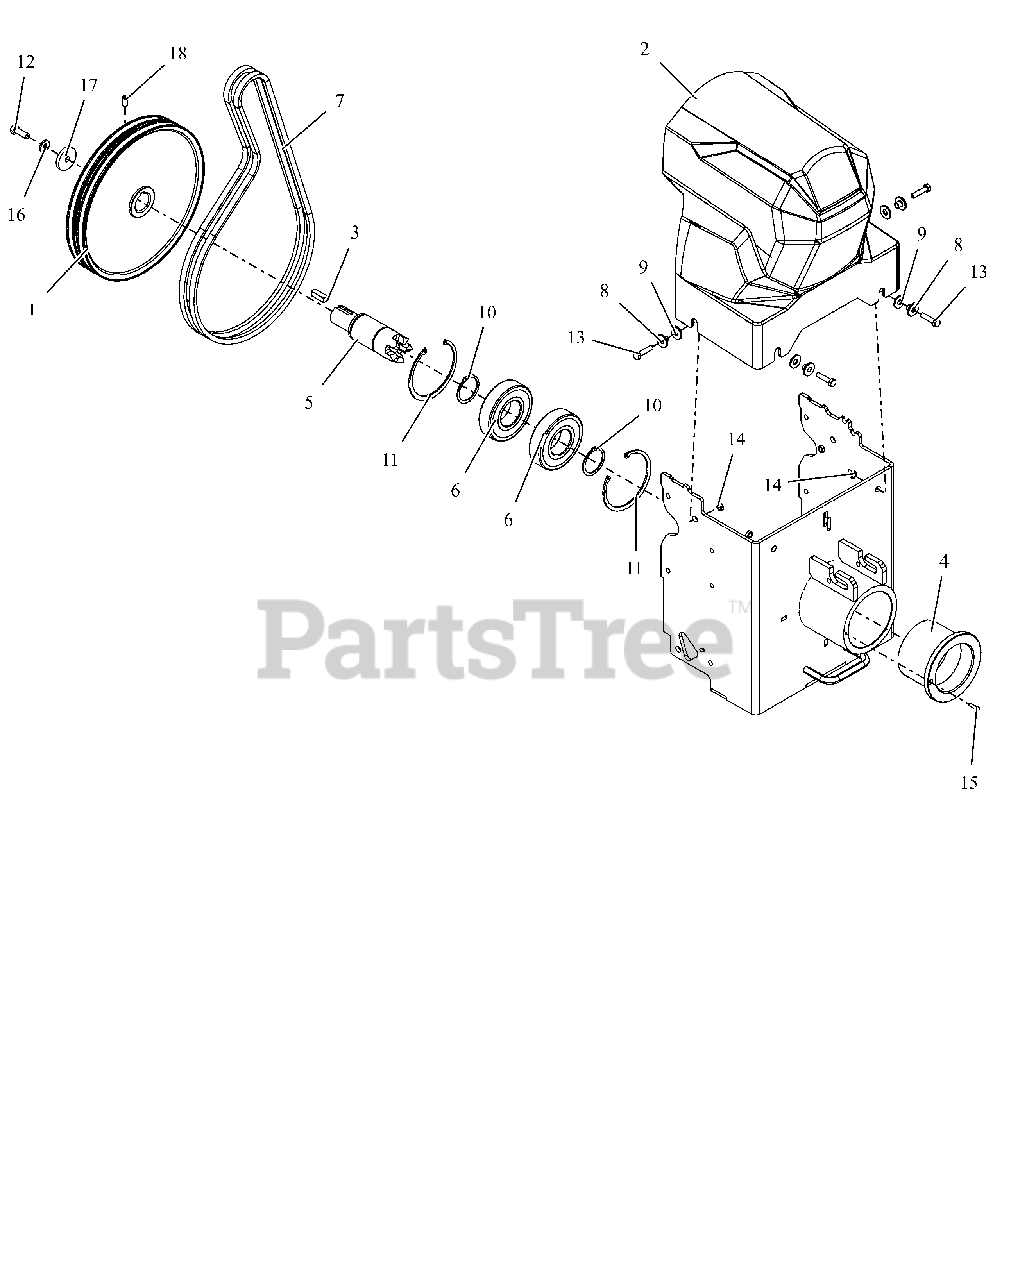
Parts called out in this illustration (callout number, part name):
1	PULLEY, DBL PTO INPUT
2	COVER, FRONT BELT
3	KEY-SQ .38X1.25X.375
4	BUSHING, OUTPUT
5	SHAFT, PTO
6	BRG, BALL 6310-2RS
7	V-BELT,HA DBLCLUTCHCOVER(SET)
8	BSHG, BELT COVER
9	WSHR,.093X.425X1.000 EPDM 50A
10	RING, RETAINING EXT 50 X 2MM
11	RING, RETAINING INT 4.25X.109"
12	BLT, HEX M10-1.5 X 30 G8.8 ZCC
13	BLT, HEX M8-1.25X35 GR8.8ZC120
14	NUT,NYL M8-1.25 G8.8 ZCC
15	SCR, SKH M5-.8 X 16 12.9 ZC120
16	WSHR,BLVL,M10 X 25 X 3.9 ZCMCH
17	WSHR,FLT .406X1.75X.25 ZCC
18	SCR, SET .38-24X.75 SK CUP
